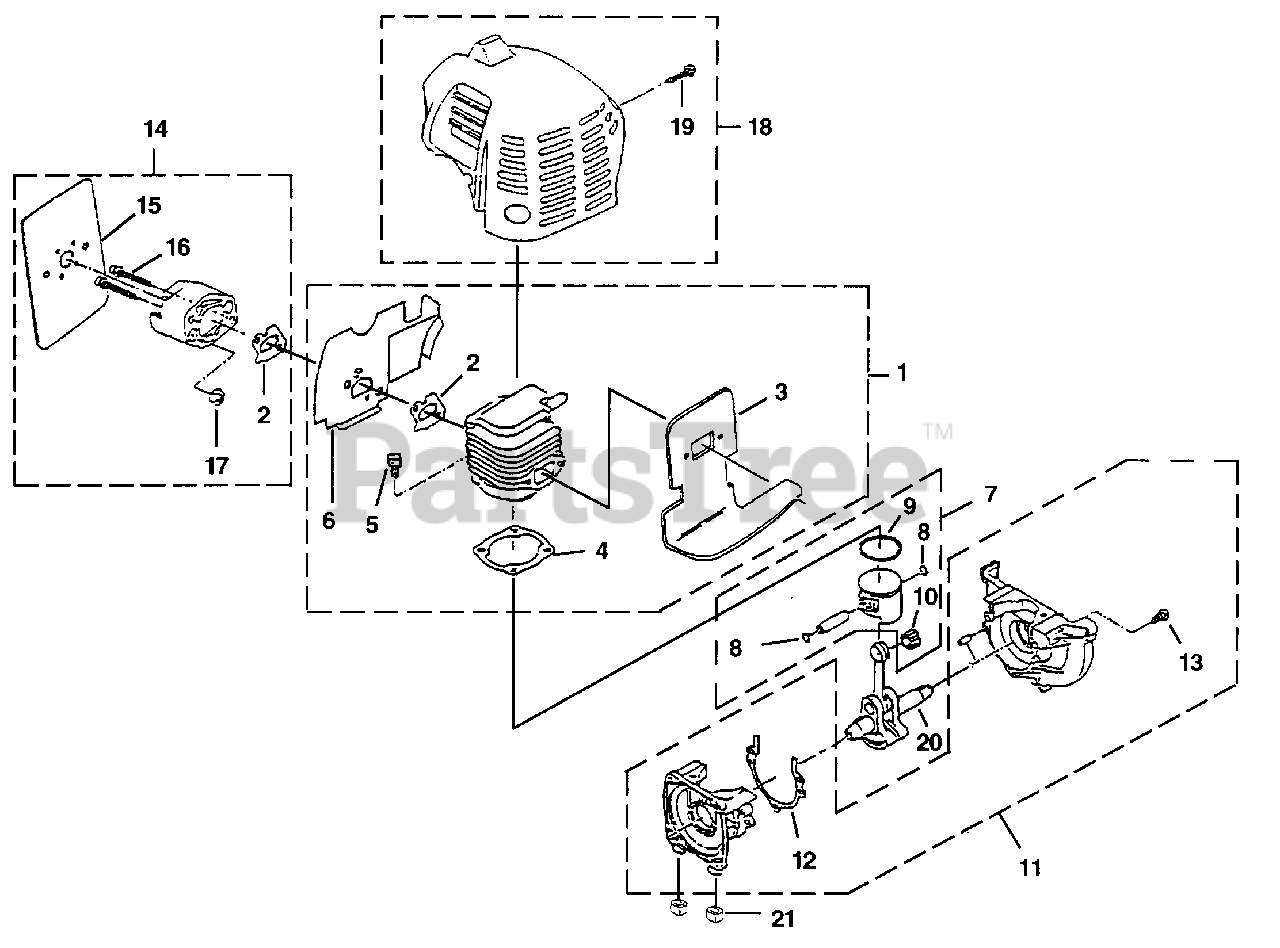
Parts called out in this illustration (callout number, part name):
1	CYLINDER ASSEMBLY
2	GASKET-Heat Dam
3	GASKET-Muffler
4	GASKET-Cylinder
5	SCREW-Socket HD (M5 x 20 SW)
6	INSULATOR-Carburetor
7	PISTON ASSEMBLY
8	RING-Retaining
9	RING-Piston
10	BEARING-Wrist Pin
11	CRANKCASE ASSEMBLY
12	GASKET-Crankcase
13	SCREW (M5 x 25)
14	HEAT DAM ASSEMBLY W/Nuts
15	GASKET-Carburetor
16	SCREW-Socket Hd (M5 x 20)
18	CYLINDER COVER
19	SCREW (M5 x 14)
20	CRANKSHAFT
21	RUBBER BUMPER KIT
